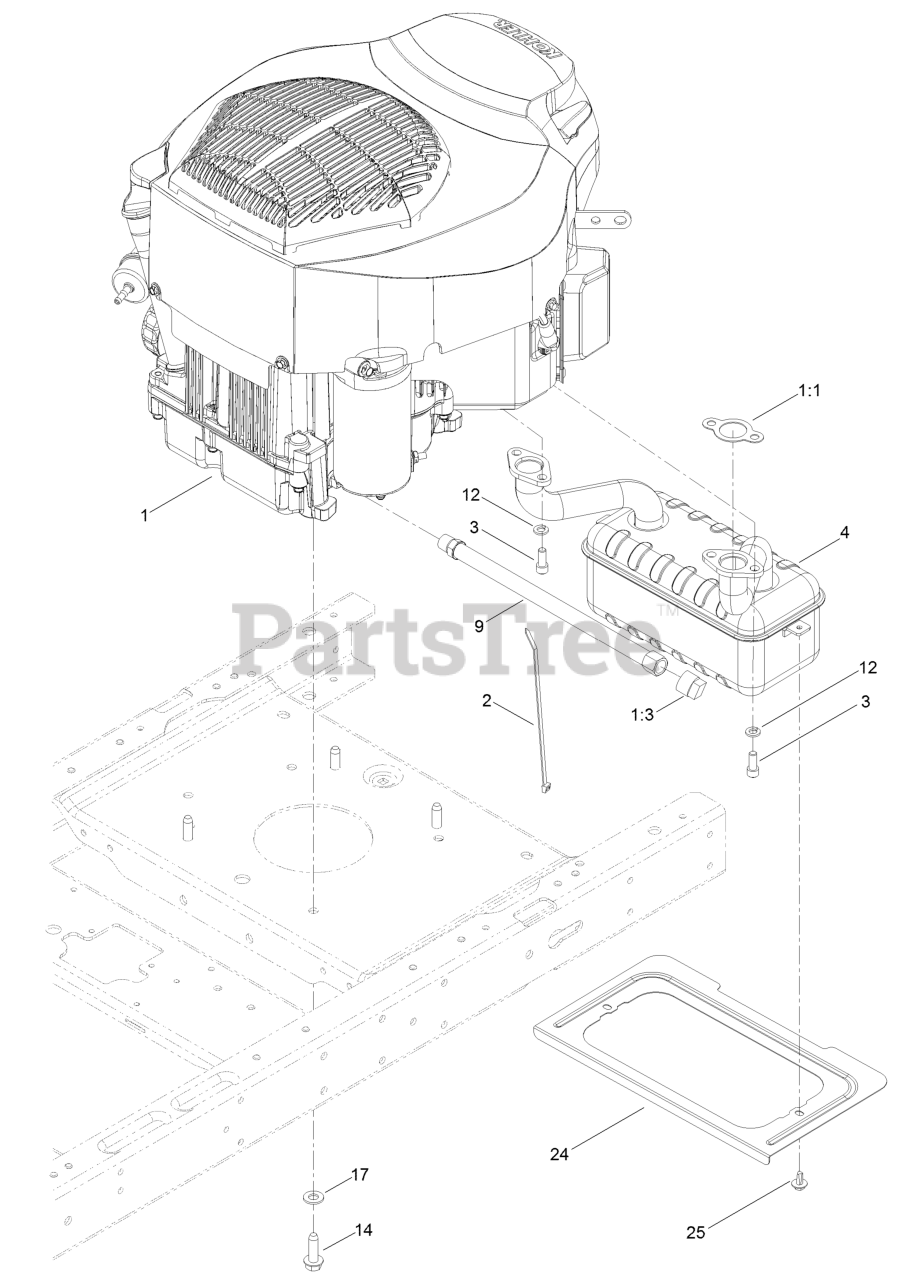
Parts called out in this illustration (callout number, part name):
1	Engine-Kohler 22HP 7000 Series Autochoke
1:1	GASKET-EXHAUST
1:3	PLUG-PIPE, SQH
2	TIE-CABLE
3	SCREW-HSH
4	MUFFLER-KOHLER
9	HOSE-DRAIN, OIL
12	WASHER-LOCK
14	SCREW-THD
17	WASHER-FLAT
24	SHIELD-HEAT
25	SCREW-HHFTF
